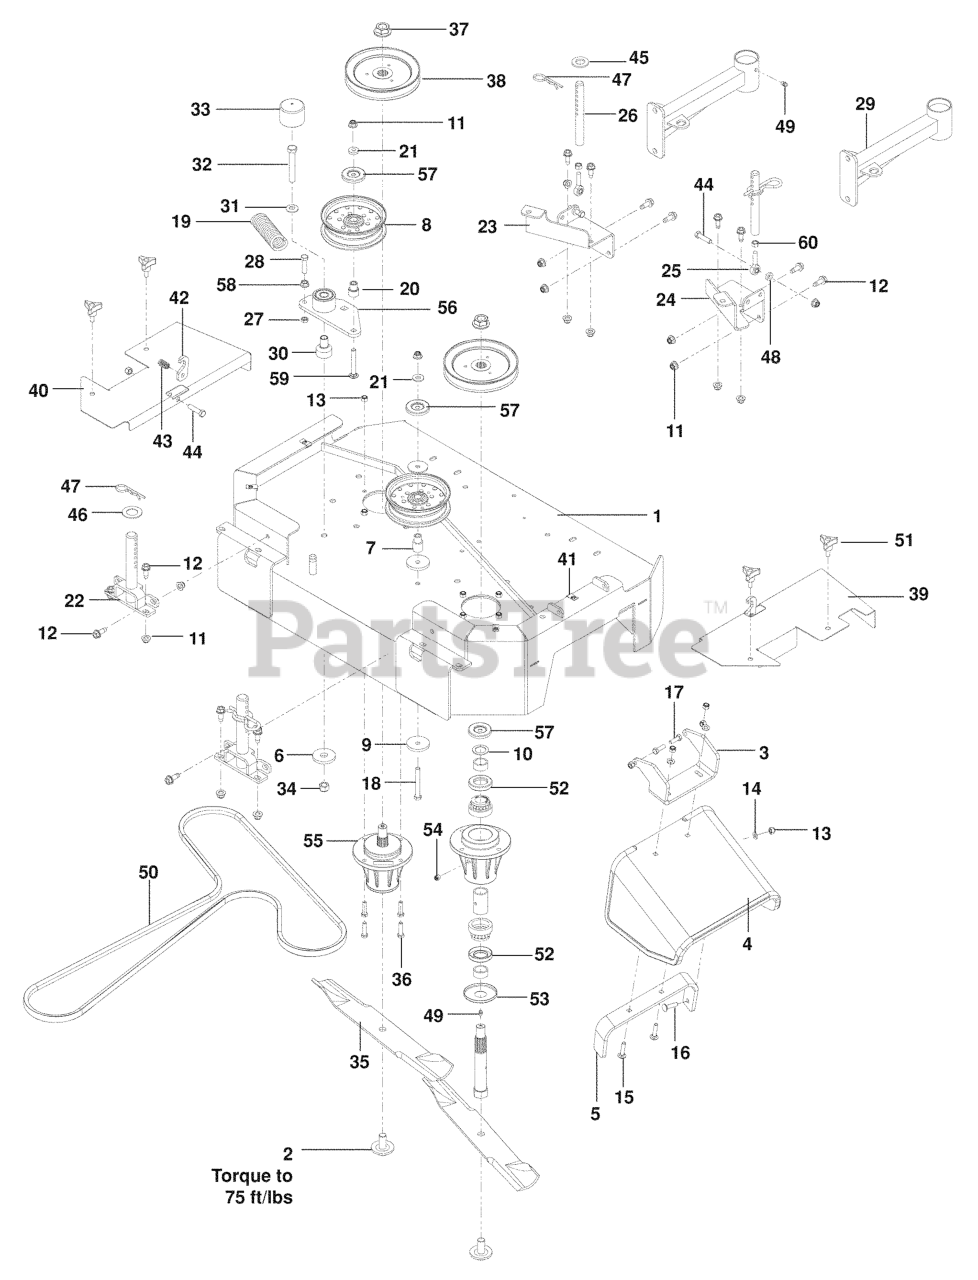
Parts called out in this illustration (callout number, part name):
1	CUTTER DECK 36" W/DECALS
2	BLADE BOLT/WASHER
3	HINGE CHUTE - BLACK
4	CHUTE, RUBBER DISCHARGE WB
5	BRKT, REINF-CHUTE WB
6	WASHER, SUPPORT
7	IDLER BUSHING
8	IDLER PULLEY
9	SPINDLE WASHER
10	MACHINE BUSHING
11	NUT 3/8-16 HEX FLG NYLOC
12	BOLT 3/8-16 x 1 THD FRM
13	NUT 5/16 NYLOC
14	FLAT WASHER 5/16 SAE
15	RHSNB 5/16-18 X 1-1/2 GR 5 ZD
16	BOLT, CARRIAGE 5/16X1-1/4
17	HCS 5/16C X 1
18	HCS 3/8C X 3
19	SPRING, EXT
20	BUSHING, IDLER
21	WASHER, 3/8 THICK
23	SUPPORT, FRONT LH OR
24	SUPPORT, FRONT RH OR
25	ROD END - 3/8-24 RH
27	NUT 3/8-16 HEX JAM
28	HCS 3/8-16 X 1-1/2
29	SUPPORT, CASTER 36 OR
30	PIVOT, BEARING
31	CONTACT BELLSPR 1/2
32	HCS 1/2C X 3 1/4
33	CAP, VINYL
34	NUT 1/2-13 HEX NYLOC ZD
35	BLADE OEM 18"
36	HCS 5/16C X 1 1/4
37	NUT FLANGE 3/4-16
38	PULLEY - 6.57
39	COVER, 36 RH GY
40	COVER, 36 LH GY
41	U-CLIP 5/16-18 NUT RETAINER
43	SPRING - COMPRESSION
44	HCS 3/8C X 1 1/2
45	WASHER 3/4 FLAT SAE ZD
48	WASHER 3/8 X 3/4 X .187 TK
49	ZERK
50	V-BELT 109
51	KNOB W/STUD
52	SHAFT SEAL
53	BOTTOM DUST CAP
54	PLUG-VENTED
55	HOUSING ASM, 72
56	ARM-IDLER W/BRG
57	DUST SHIELD
58	NUT 3/8C WHIZ
59	RHSNB 3/8-16 X 2.75
